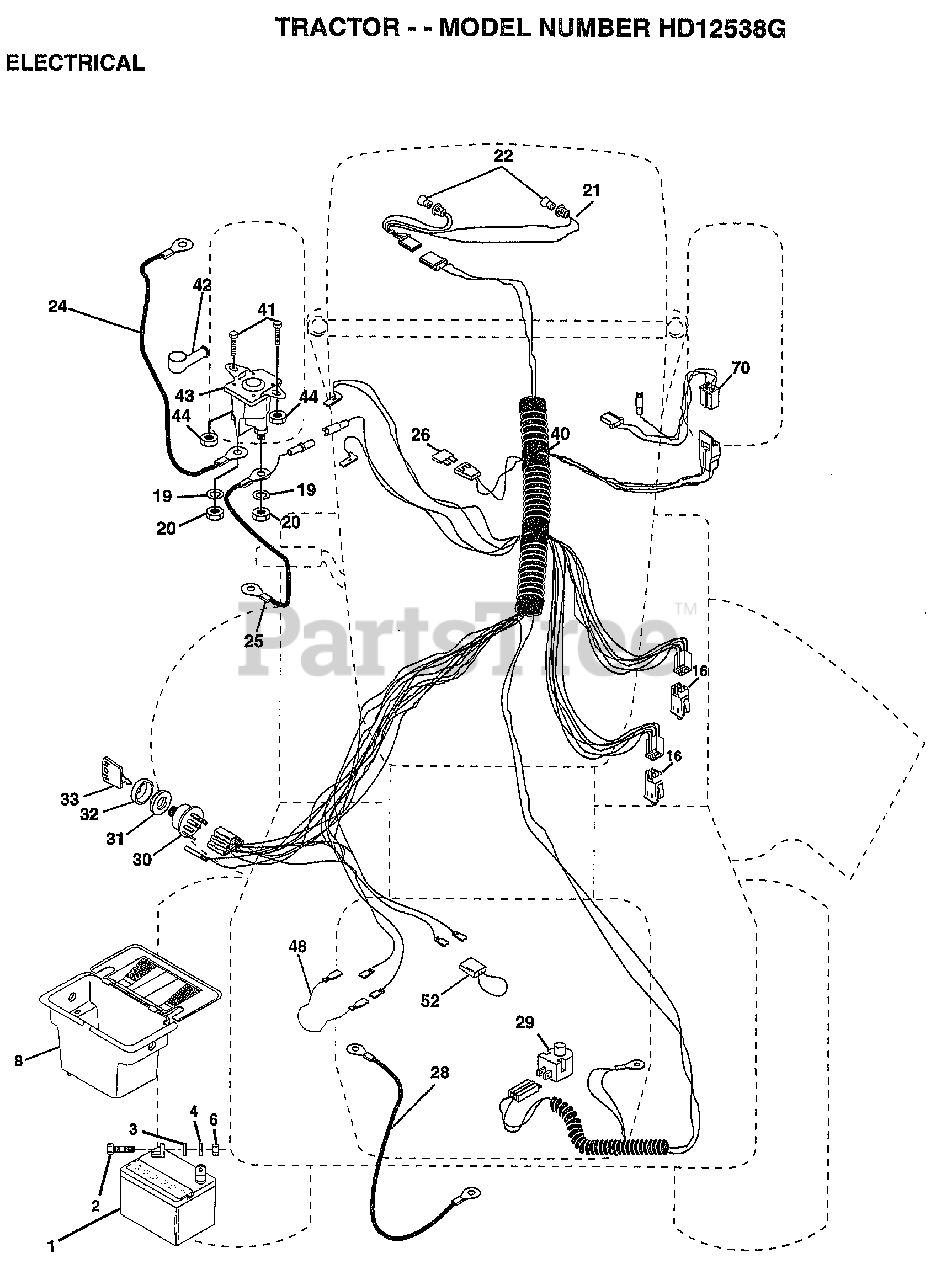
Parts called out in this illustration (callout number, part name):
3	WASHER
4	LOCKWASHER
8	"CASE,BATTERY.MECH"
16	SWITCH INTERLOCK
20	NUT
21	"HARNESS,LIGHT SOC"
22	HEADLAMP BULB
24	"CABLE T, BATTERY"
25	CABLE.BTRY.6GA.RD
26	FUSE HYT
28	CABLE T
29	SWITCH SEAT
30	SWITCH IGN 4POS
31	NUT IGNITION
32	COVER KEY SWITCH
33	KEY
40	HARNESS-IGNITION
41	BOLT HXHD FIN
44	NUT HXKEP 1/4X20
48	ADAPTER AMMETER
52	PROTECTION LOOP
70	HARNESS ENG DUAL
